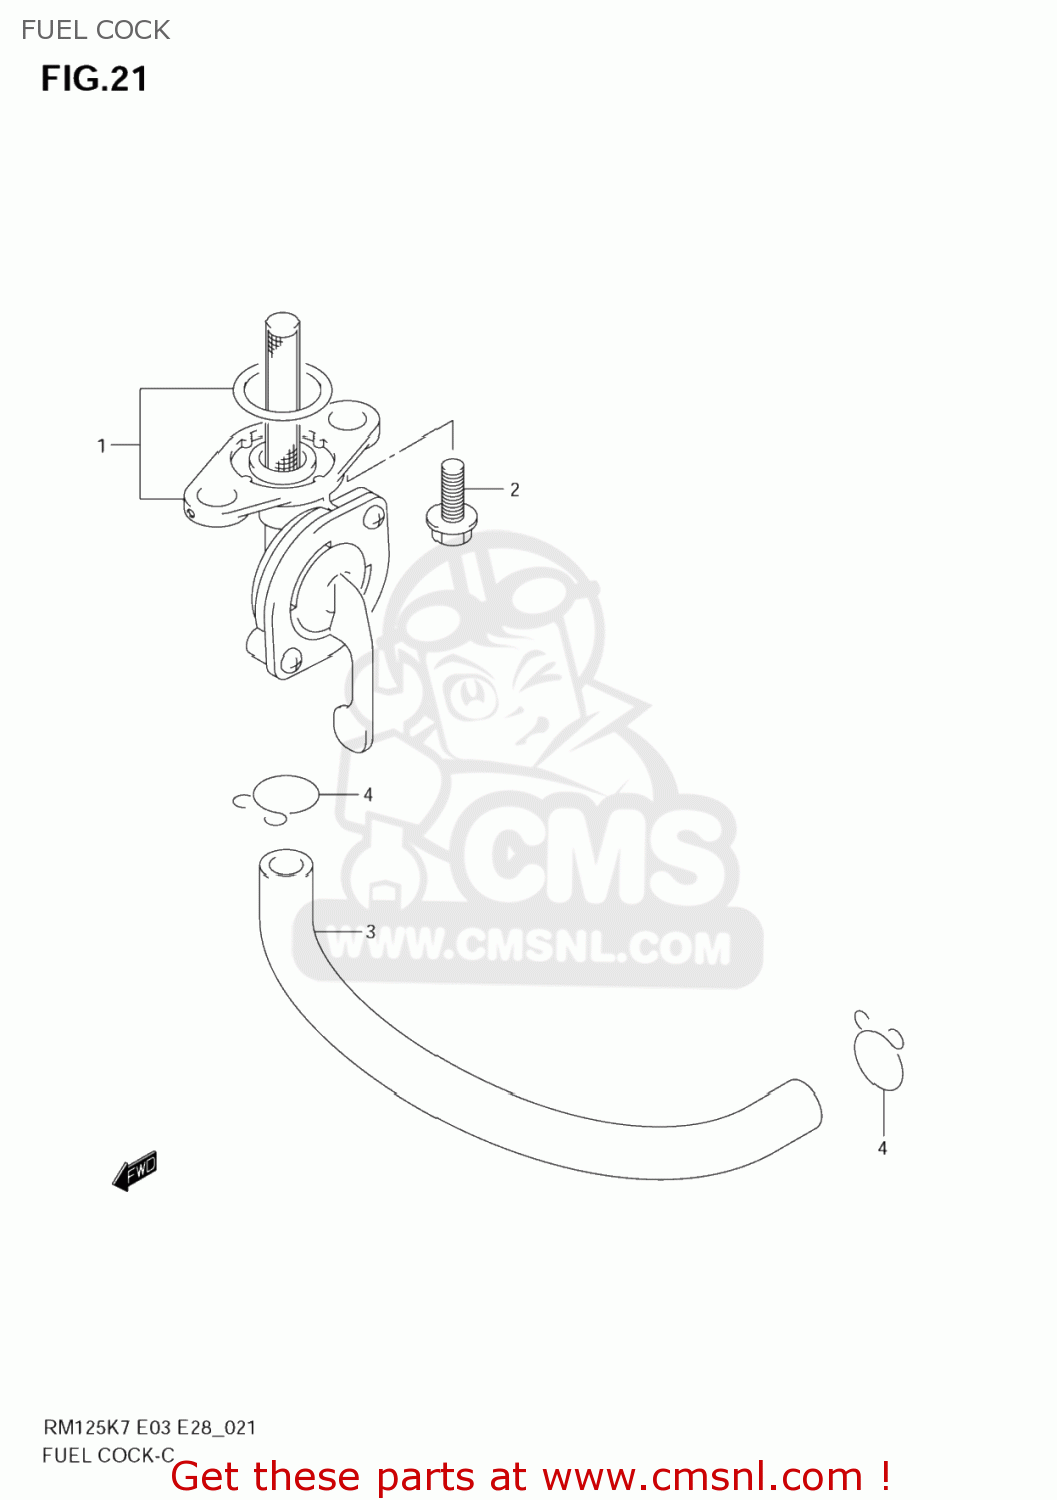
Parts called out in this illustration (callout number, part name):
1	COCK ASSY,FUEL
2	BOLT(6X16)
3	HOSE,FUEL
4	CLIP
